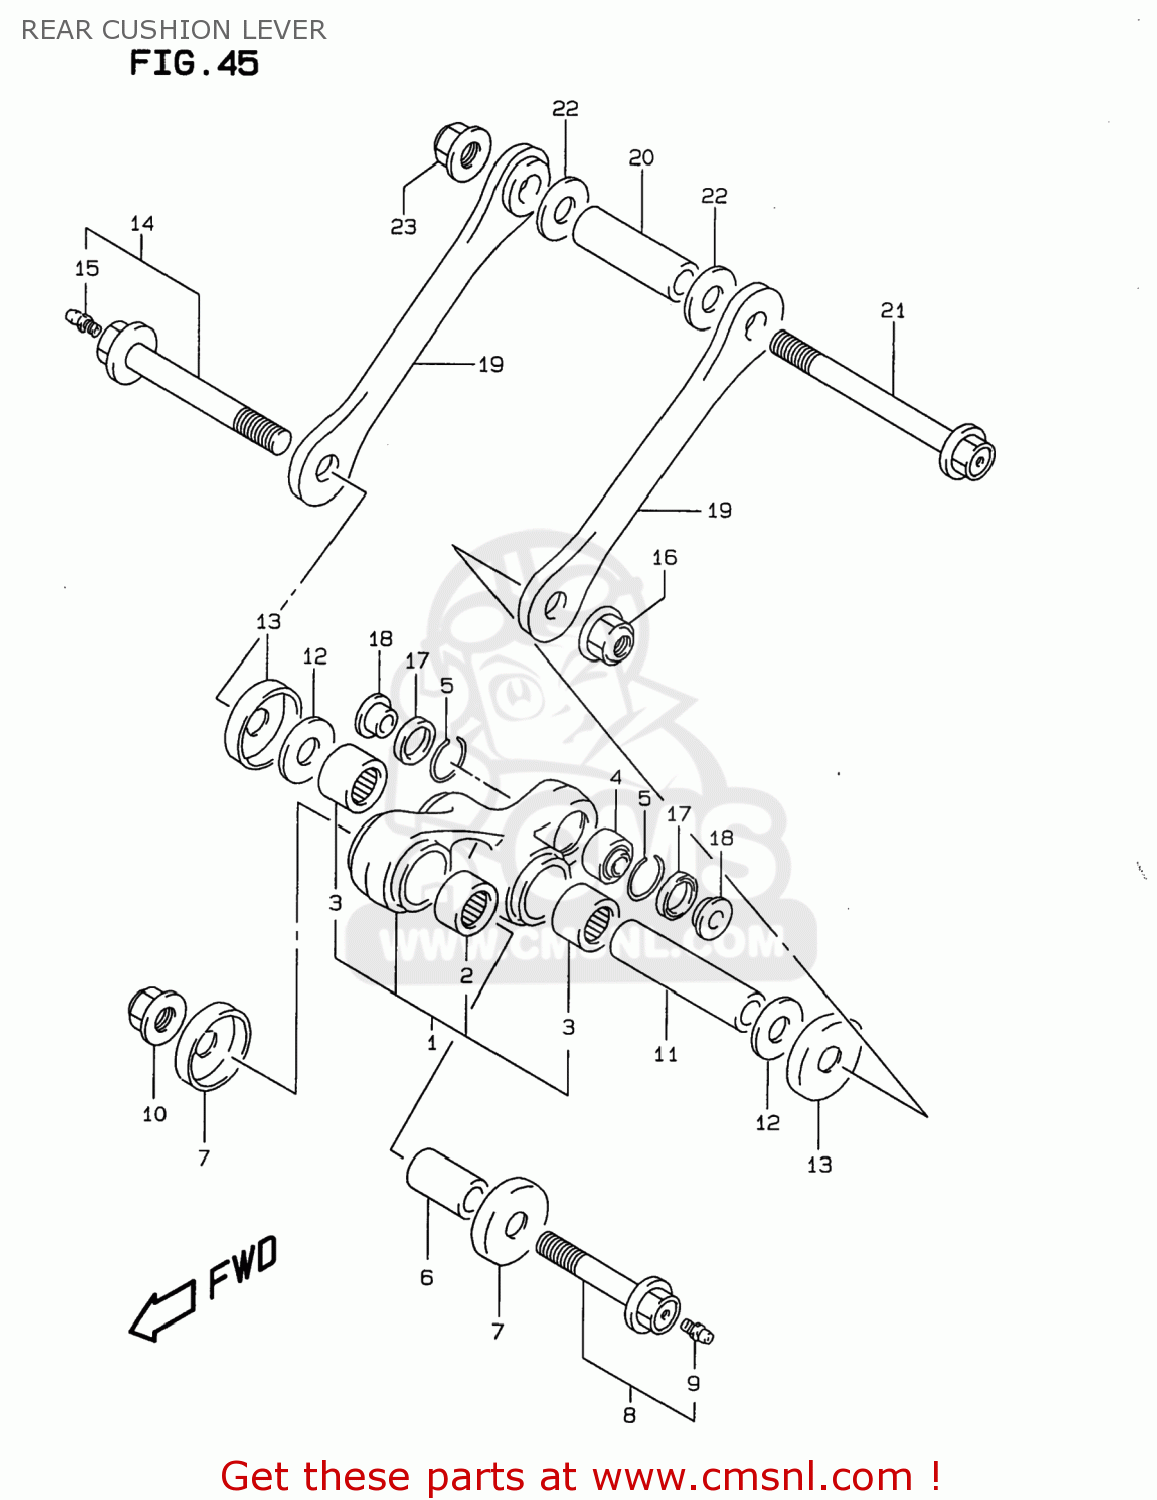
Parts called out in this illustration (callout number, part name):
1	LEVER SET,RR CUSHION
2	BEARING(20X27X32)
3	BEARING(20X27X23.5)
4	BEARING,RR CUSHION LEVER
5	RING,STOPPER
6	SPACER,RR CUSHION LEVER FR
7	SEAL,RR CUSHION LEVER FR DUST
8	BOLT,RR CUSHION LEVER FR
9	GREASE NIPPLE
10	NUT 12MM
11	SPACER,RR CUSHION LEVER CTR
12	WASHER
13	SEAL,RR CUSHION LEVER
14	BOLT,RR CUSHION LEVER CTR
15	GREASE NIPPLE
16	NUT
17	SEAL,OIL(17X24X3)
18	COLLAR
19	ROD,RR CUSHION
20	SPACER,RR CUSHION ROD
21	BOLT,RR CUSHION ROD
22	WASHER
23	NUT
